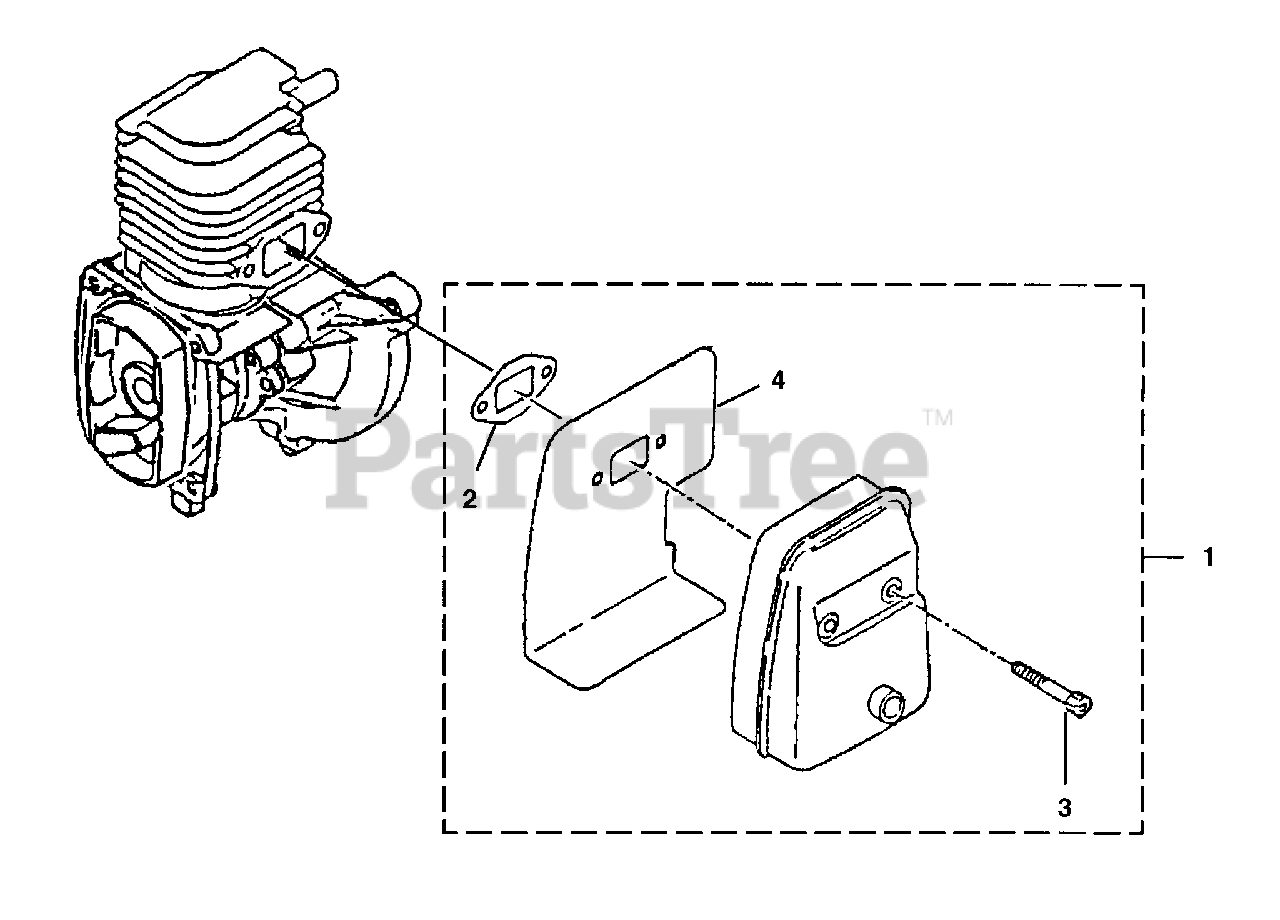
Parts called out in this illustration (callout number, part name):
1	MUFFLER ASSEMBLY
2	GASKET-Muffler
3	SCREW-Socket Hd (M5 x 55)
4	INSULATOR-Muffler
